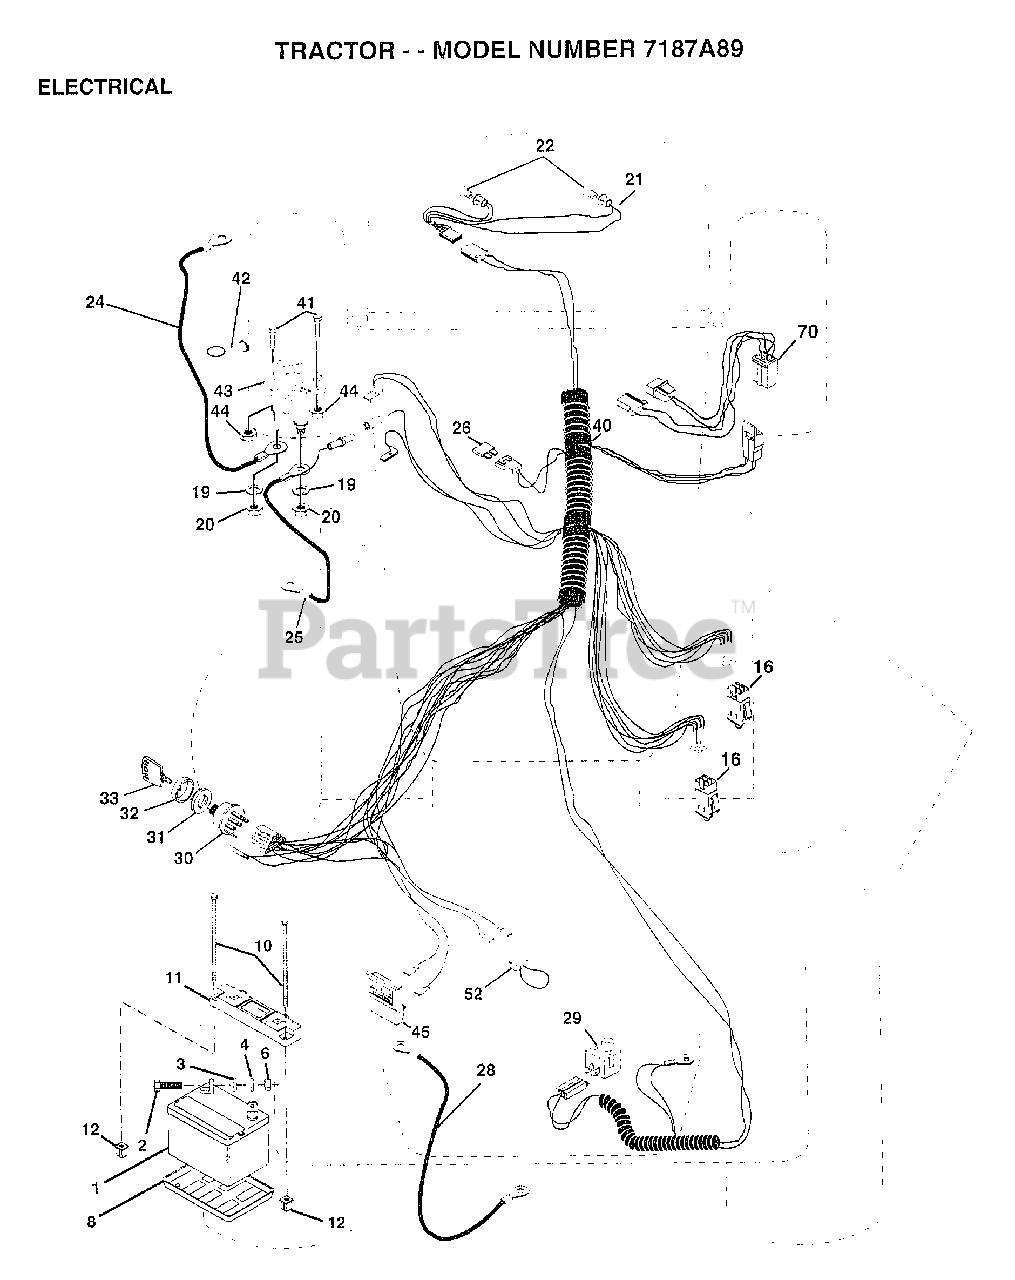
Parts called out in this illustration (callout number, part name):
3	WASHER
4	LOCKWASHER
8	TRAY BATTERY
11	HOLDDOWN BATTERY
16	SWITCH INTERLOCK
20	NUT
21	"HARNESS,LIGHT SOC"
22	HEADLAMP BULB
24	"CABLE T, BATTERY"
25	CABLE.6GA.22W/16W
26	FUSE HYT
28	CABLE.GRND.6GA.21
29	SWITCH SEAT
30	SWITCH IGN 4POS
31	NUT IGNITION
32	COVER KEY SWITCH
33	KEY
40	HARNESS-IGNITION
41	BOLT HXHD FIN
44	NUT HXKEP 1/4X20
52	PROTECTION LOOP
55	SCREW LT
70	HARNESS.ENG.DUAL
